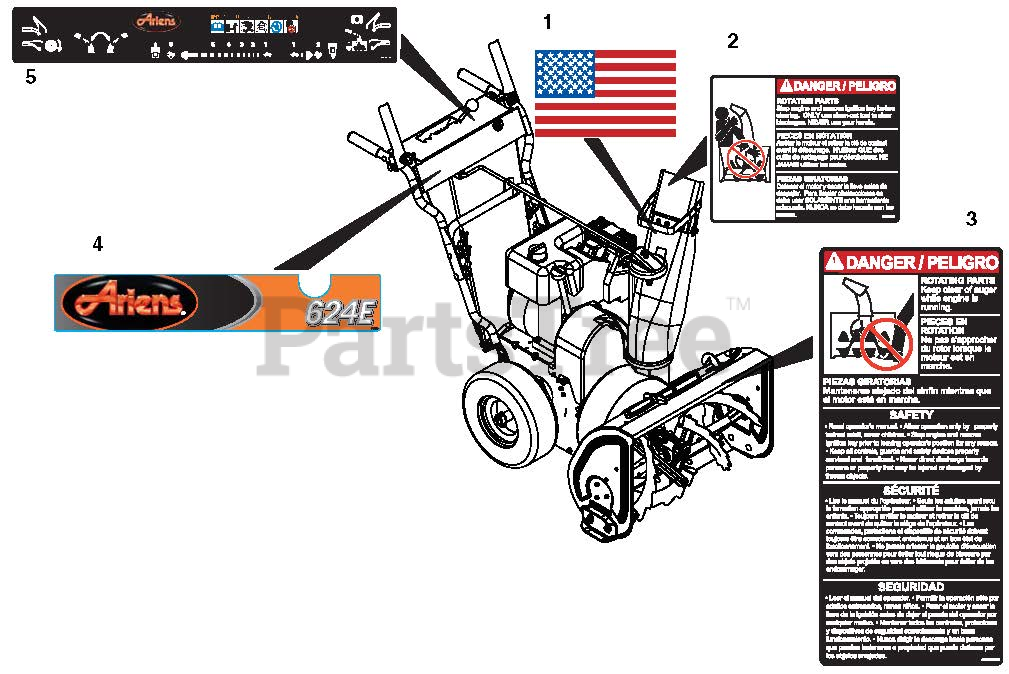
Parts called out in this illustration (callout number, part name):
1	DECAL, AMERICAN FLAG
2	DECAL, DANGER - ROT. PARTS
3	DECAL, DANGER
4	DECAL, DASH - 624E
5	DECAL, CONTROL, COMPACT/DELUXE
